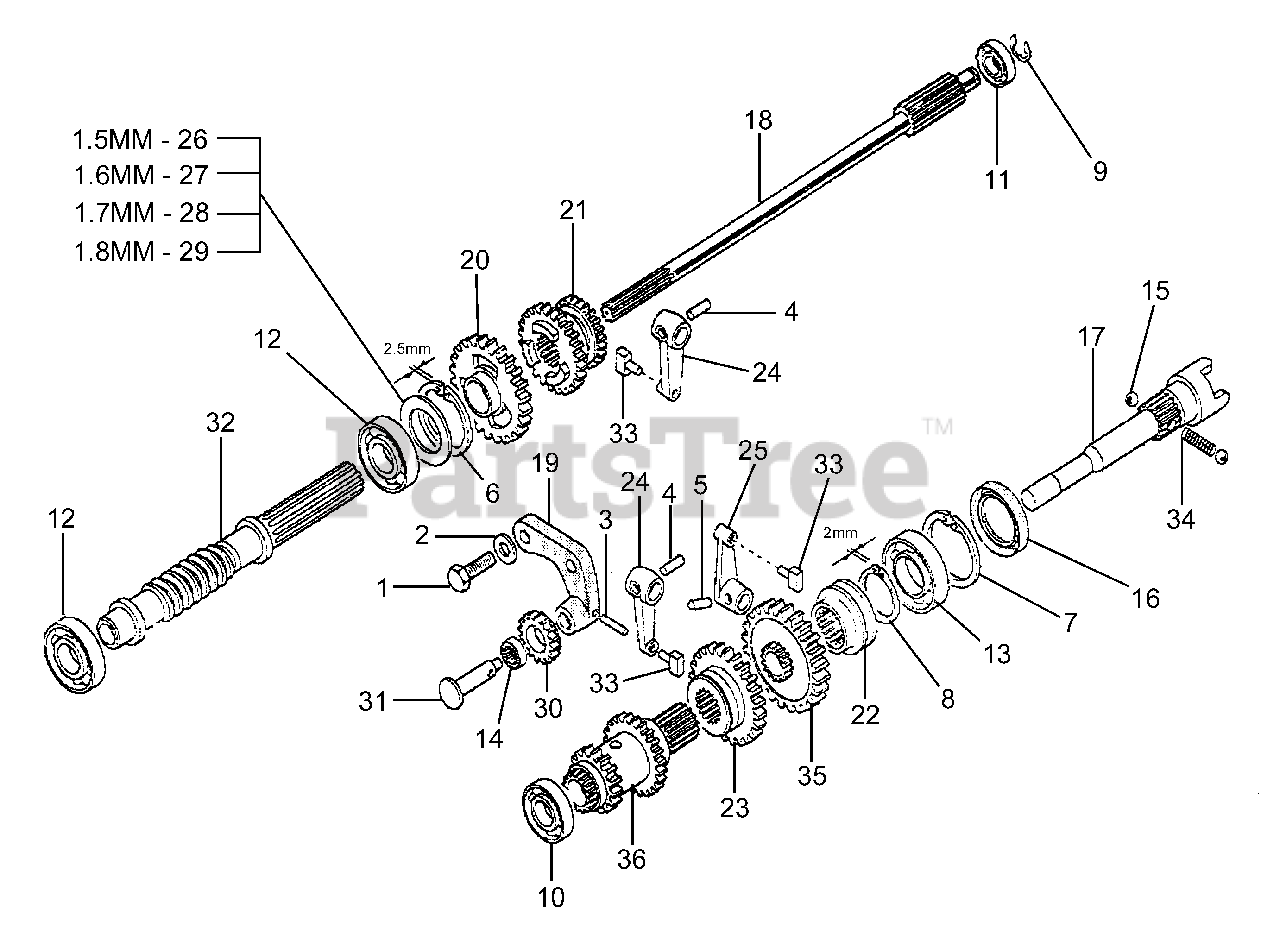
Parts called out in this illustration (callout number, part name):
1	HEX. SCREW M10X30 UNI 5739-8G
2	TOP WASHER 10
3	ROLL PIN 4X25
4	ROLL PIN 6X24 SPIROL
5	ROLL PIN 6X20 SPIROL U.6876
6	SNAP RING INS.D52 PES.UNI7438
7	SNAP RING INS.D 55 DIN 472
8	SNAP RING OUTS.30 S.HVY U7436
10	BEARING 6202 15X35X11 SKF
11	BEARING 63-02-15X42X13
12	BEARING SKF 25X52X15 6205
13	BEARING 6006 30X55X13 SKF
14	BEARING K12X15X10 H
15	BALL 1/4 RIV RB 6.35
16	OIL SEAL 38X55X7
18	INPUT SHAFT
19	REVERSER GEAR MOUNT
20	GEAR/IDLER 1ST GEAR
21	SPEED SLIDING GEAR 4+3
23	REVERSER SLIDER
24	GEAR SLIDER LEVER
25	PTO SLIDER LEVER
26	SPACER RING THICKNESS=1.5
27	SPACER RING THICKNESS=1.6
28	SPACER RING THICKNESS=1.7
29	SPACER RING THICKNESS=1.8
30	REVERSER GEAR
32	WORM SCREW 2 START
34	PTO SLIDING SPRING
35	PTO GEAR COMPL.
36	TRIPLE GEAR
